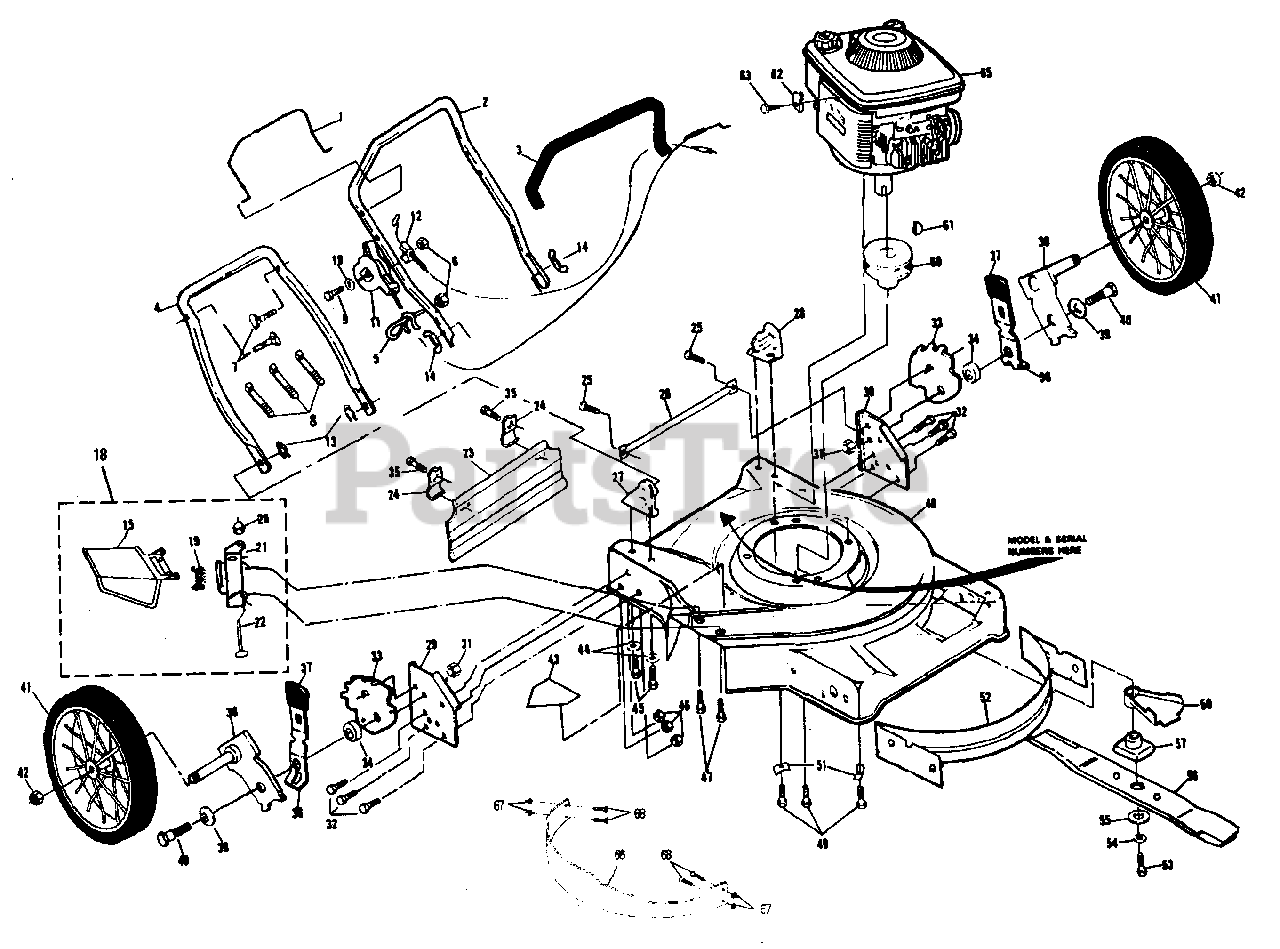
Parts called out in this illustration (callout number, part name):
1	Control Bar (AYP part number)
2	Upper Handle (AYP part number)
3	Handle Grip (AYP part number)
4	Lower Handle (AYP part number)
5	Rope Guide
6	Locknut 1/4-20 (AYP part number)
7	Handle Bolt 5/16-18 x 1-3/4 (AYP part number)
8	Wire Tie (AYP part number)
9	Machine Screw 1/4-20 x 2-1/8 (AYP part number)
10	Washer (AYP part number)
11	Throttle Control (AYP part number)
12	Engine Zone Control Cable
13	Hairpin Cotter (AYP part number)
14	Handle Knob (AYP part number)
15	Discharge Guard
18	Discharge Guard Assembly (AYP part number)
19	Torsion Spring (AYP part number)
20	Speed Nut (AYP part number)
21	Housing Bracket (AYP part number)
22	Hinge Rod (AYP part number)
23	Rear Skirt (AYP part number)
24	Bracket Skirt (AYP part number)
25	Hex Tapping Screw 1/4-20 x 1/2 (AYP part number)
26	Rod Support (AYP part number)
27	Handle Bracket Assembly, Right (Yellow) (AYP part number)
28	Handle Bracket Assembly, Left (Yellow) (AYP part number)
29	Wheel Support Bracket, Right (Yellow)) (AYP part number)
30	Wheel Support Bracket, Left (Yellow)) (AYP part number)
31	Locknut 3/8-16 (AYP part number)
32	Hex Head Bolt 3/8-16 x 3/4 (AYP part number)
33	Wheel Adjuster Bracket (AYP part number)
34	Spacer (AYP part number)
35	Screw Hex Washer Head Tapping (AYP part number)
36	Selector Spring (AYP part number)
37	Selector Knob
38	Axle Arm Assembly (AYP part number)
39	Washer (AYP part number)
40	Shoulder Bolt 3/8-16 (AYP part number)
41	Wheel & Tire Assembly (AYP part number)
42	Hex Flange Locknut 3/18-16 (AYP part number)
43	Danger Decal (AYP part number)
44	Washer (AYP part number)
45	Screw (AYP part number)
46	Locknut 3/8-16 (AYP part number)
47	Hex Head Thread Rolling screw w/Sems 1/4-20 (AYP part number)
48	Lawn Mower Housing
49	Hex Head Thread Rolling Screw 3/8-16 x 1 (AYP part number)
50	Debris Shield
51	Engine Washer (AYP part number)
52	Front Baffle (AYP part number)
53	Hex Head Screw 3/8 x 24 x 1-3/8 Grade 8
54	Helical Lockwasher 3/8 (AYP part number)
55	Hardened Washer (AYP part number)
56	Mulcher Blade (AYP part number)
57	Blade Adapter
60	Engine Pulley (AYP part number)
61	Hi-Pro key #HP-505 (AYP part number)
62	Cable Clamp (AYP part number)
63	Screw 10 x 5/8 (AYP part number)
66	Baffle Mulcher (AYP part number)
67	Nut, Hex Lock (AYP part number)
68	Screw Machine 10-24 x 1/2 (AYP part number)
